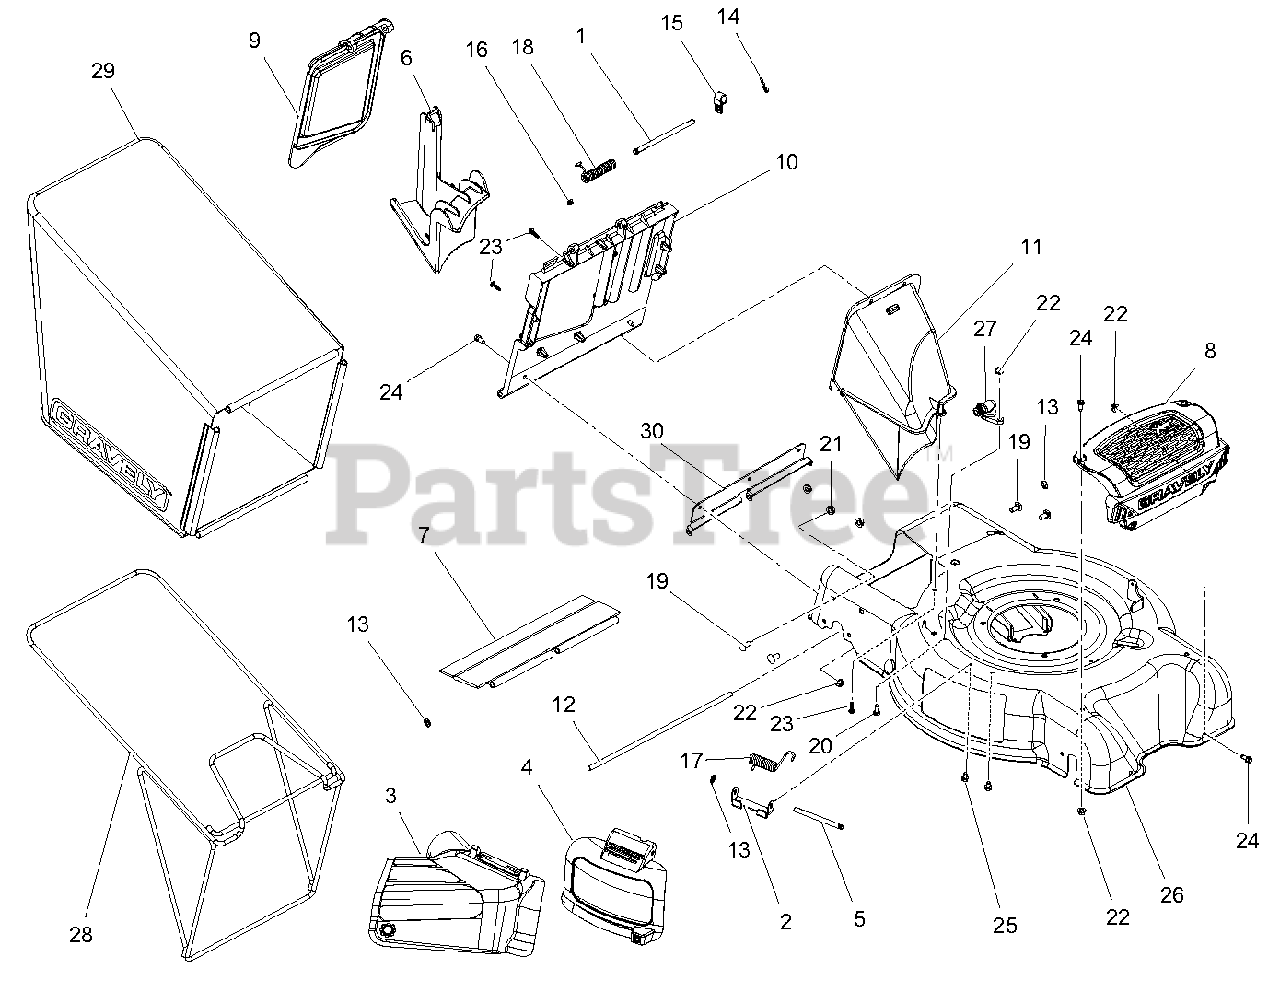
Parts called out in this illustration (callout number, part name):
1	PIN, 5/16 X 5.80"
2	BRKT, HINGE LM
3	CHUTE, SIDE DISCHARGE - LM
4	COVER, SIDE DISCHARGE - LM
5	PIN, SIDE DISCHARGE
6	PLUG, MULCH
7	GUARD, REAR
8	TRIM, FRONT
9	REAR DOOR WITH SAFETY DECAL
10	HANGER, BAG
11	CHUTE, REAR DISCHARGE
12	ROD, REAR GUARD
13	NUT, PUSH .312
14	PIN, HAIR INT .08X.18X1.18 Y
15	CLAMP, LM CABLE
16	PLUG, 5/16 HOLE, .125 MATL PLASTIC
17	SPRG, TORSION
18	SPRG, TORSION
19	@BLT-RDHDSQNK .31-18X.75 G5 YWZC
20	@BLT-HEX .25-20X.63 GR5 YWZC
21	@NUT, LK-TOP-FLG .312-18 YWZC
22	@NUT, LK-TOP-FLG .25-20 YWZC
23	SCR-TAP #12-14X.75 PLASTITE BLZC
24	SCR-TAP .25-20X.62 HWH TR YWZ
25	SCR-TAP .25-20X.37 HWH YWZ TR
26	DECK WITH SAFETY DECAL
27	ASM, WASHOUT PORT W/ O-RING
28	FRAME, BAGGER
29	BAGGER, GRASS GRAVELY
30	BRKT, DROP, TRAILING SHIELD
